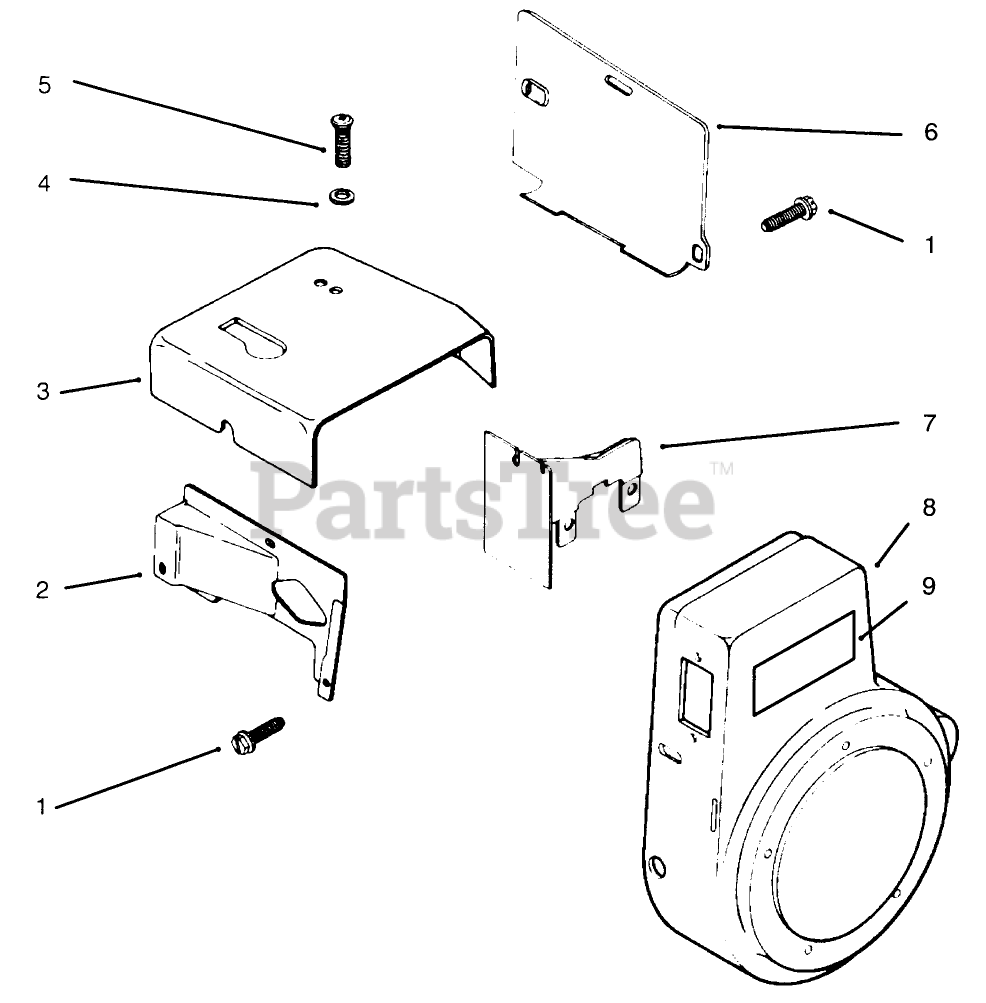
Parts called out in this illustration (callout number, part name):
1	Screw-Hex Hd
2	Baffle-Side Air
3	Baffle-Head
4	Washer
5	Screw, F.H.
6	Baffle-Cylinder
7	Baffle-Inner
8	Housing-Blower
9	Decal-14hp
